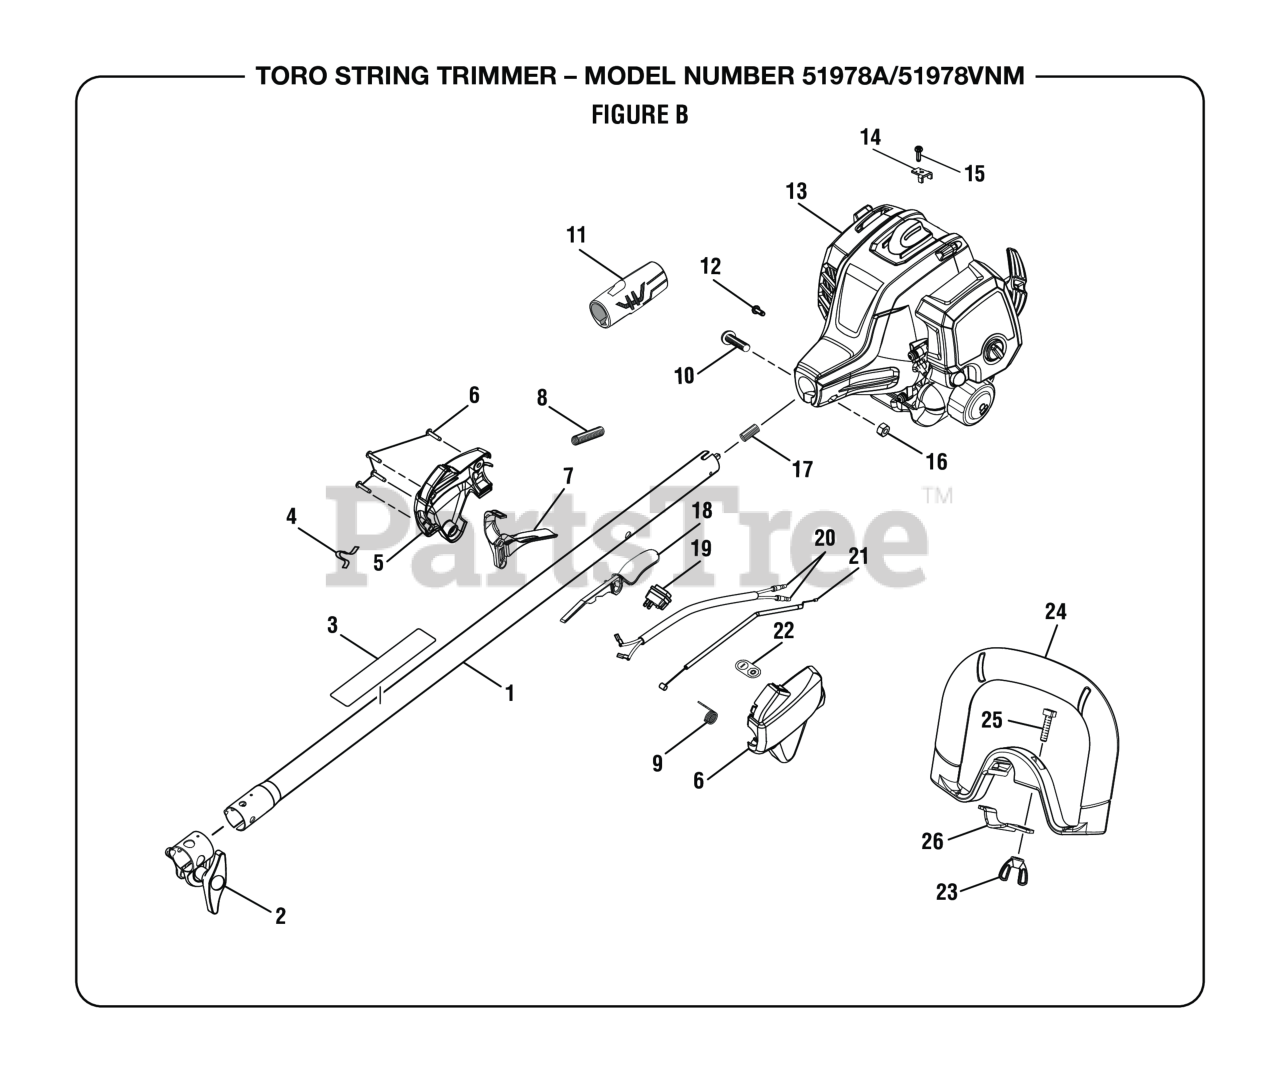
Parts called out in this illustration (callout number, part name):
1	Upper Boom Assembly
2	Boom Clamp Assembly
3	Warning Icon Label
4	Shoulder Strap Hook
5	Control Handle Assembly
6	Screw (M4 x 20 mm, T20 Torx Pan Hd. S.T.)
8	Corrugated Tube (225 mm)
9	Torsion Spring (Throttle Trigger)
10	Screw (M6 x 30 mm, T27 Torx Button Hd.)
11	Rear Handle Grip
12	Screw (M4 x 8 mm, T25 Torx Pan Hd. T.F.)
13	Powerhead Assembly
14	THROTTLE CABLE CLAMP
15	Screw (M4 x 16 mm, T20 Torx Pan Hd. S.T.)
16	Hex Nut (M6.3 x 1)
17	COMPRESSION SPRING
18	Trigger Lock
19	On/Stop Switch
20	Lead Assembly
21	Throttle Cable
22	On/Stop Label
23	Wing Nut (1/4-20, Plastic)
24	Front Handle w/Grip
25	Bolt (1/4-20 x 1 in., Square Hd.)
26	Front Handle Clamp
